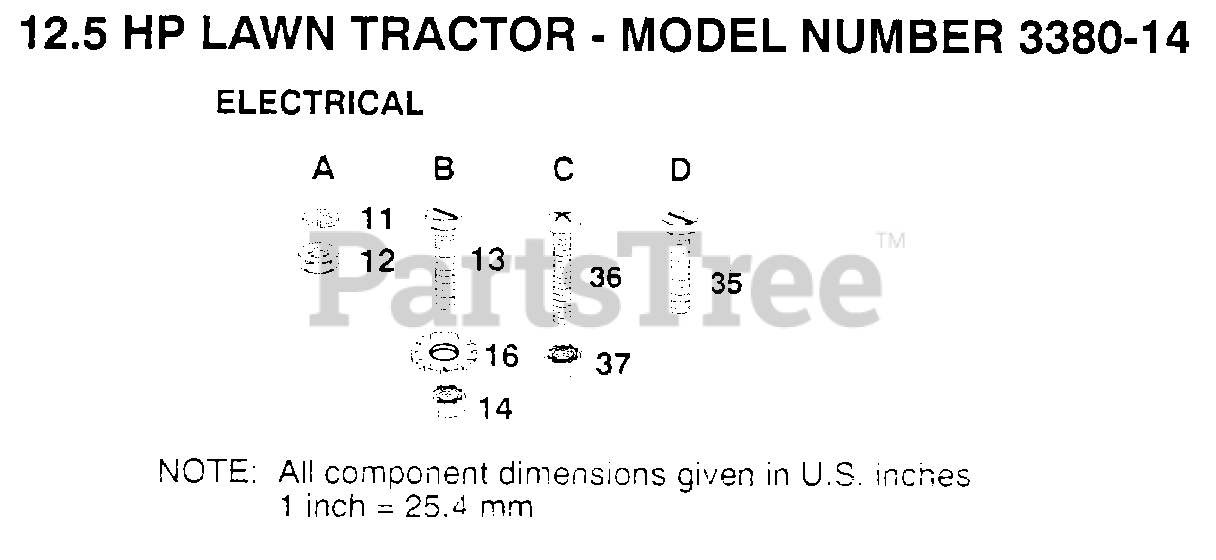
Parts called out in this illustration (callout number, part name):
12	NUT
13	BOLT
14	NUT
35	SCREW
37	"NUT,KEPS"
